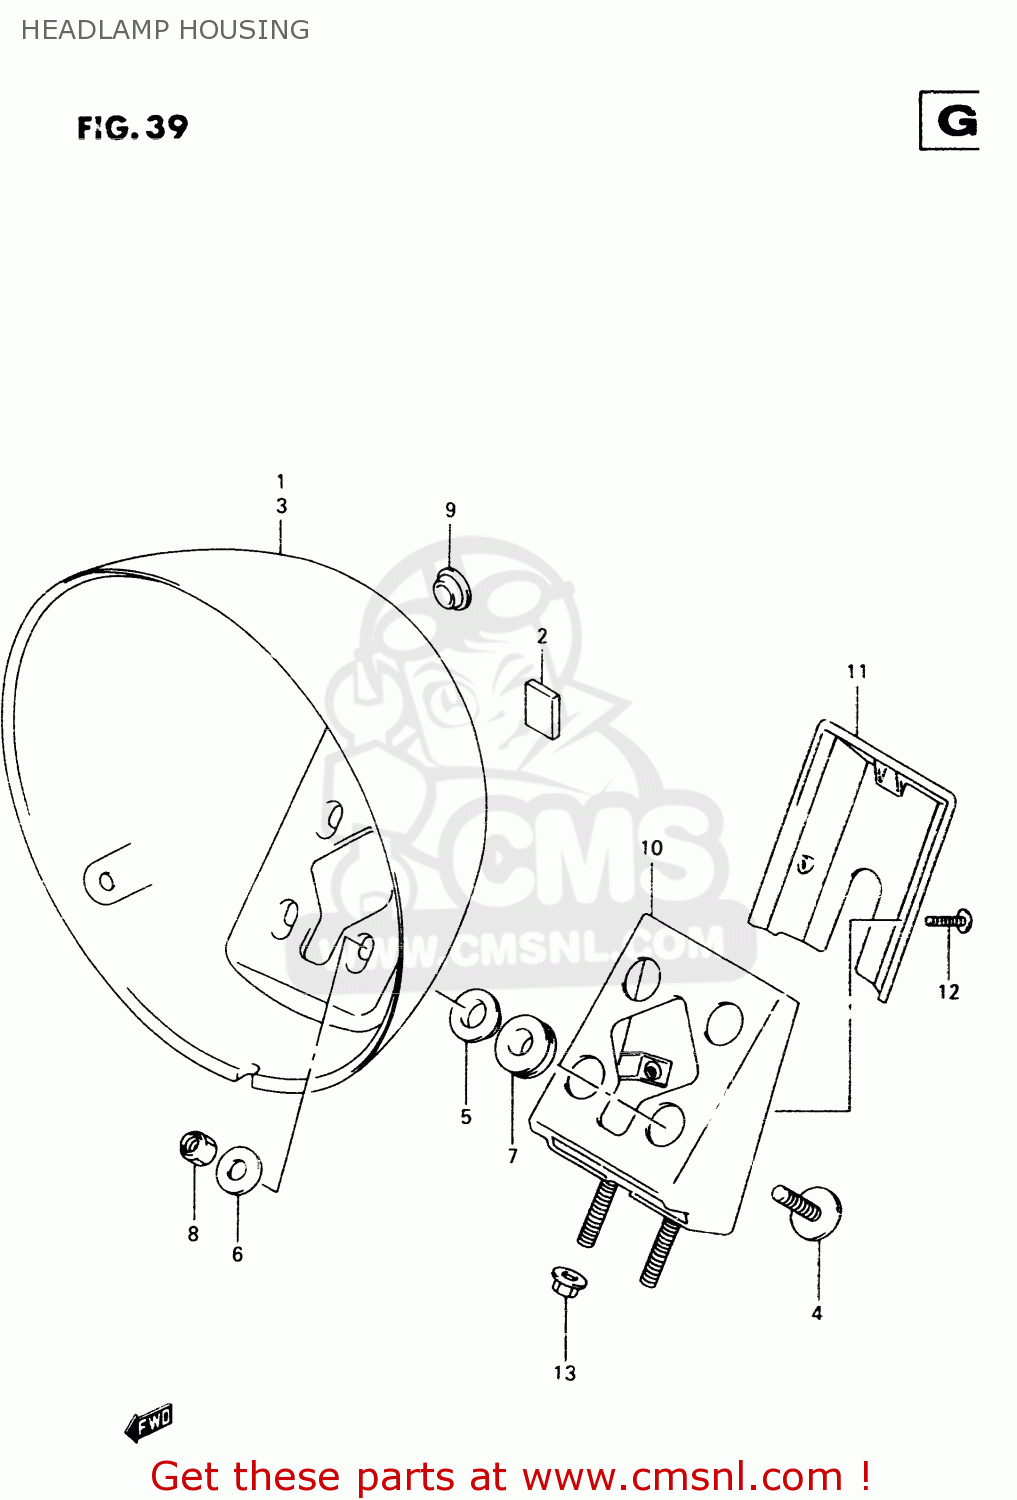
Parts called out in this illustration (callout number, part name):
1	HOUSING,HEADLAMP
2	CUSHION,HEADLAMP HOUSING
3	HOUSING,HEADLAMP
4	BOLT(6X25)
5	WASHER
6	WASHER(6.5X22X2.3)
7	CUSHION
8	NUT
9	CAP,HEADLAMP HOUSING
10	BRACKET,HEADLAMP HOUSING
11	COVER,HEADLAMP HSG BRACKET
12	SCREW
13	NUT
